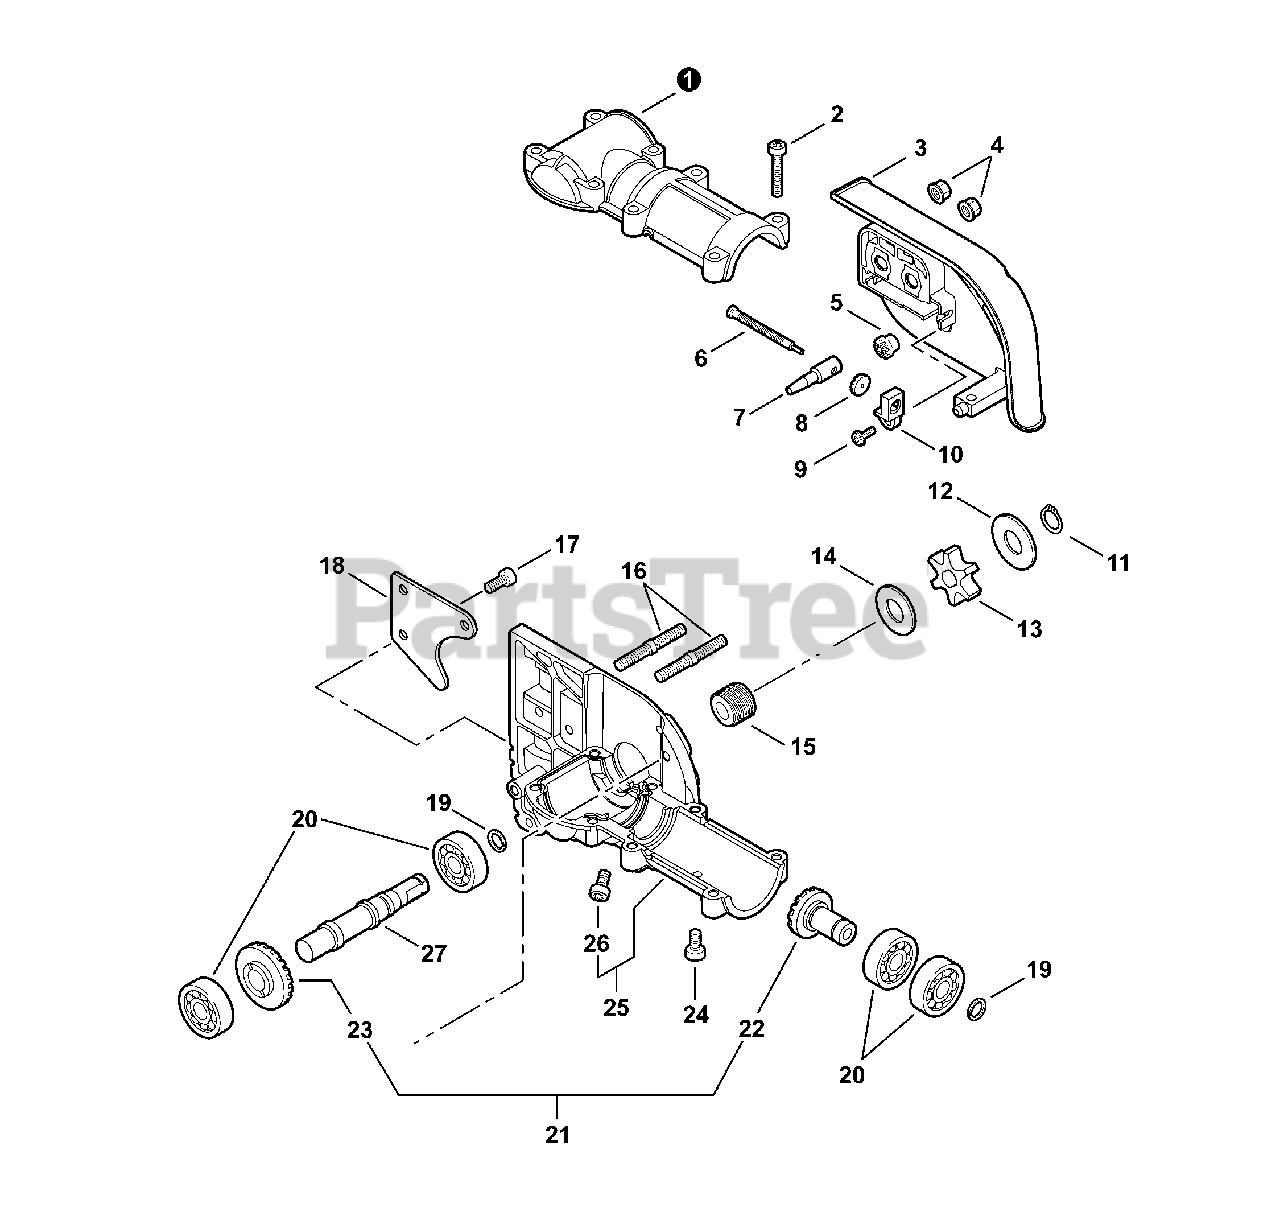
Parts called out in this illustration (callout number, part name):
1	CASE, GEAR - UPPER
2	SCREW - 5×25
3	GUARD, SPROCKET
4	NUT - 6 -- FLANGE
5	GEAR - 14 TOOTH
6	SCREW, TENSIONER
7	TENSIONER, CHAIN
8	GEAR - 14 TOOTH
9	SCREW - 4×8
10	BRACKET, TENSIONER
11	RING, RETAINING
12	WASHER - 10
13	SPROCKET, DRIVE
15	GEAR, WORM
16	STUD, GUIDE BAR
17	SCREW - 5×10
19	RING, RETAINING - 12
20	BEARING, BALL - 6001
21	GEAR SET
22	GEAR, BEVEL - 15 TOOTH
23	GEAR, BEVEL - 23 TOOTH
24	SCREW - 5×10
25	CASE, GEAR - LOWER
26	SCREW - 5×10
27	GEAR, SHAFT
